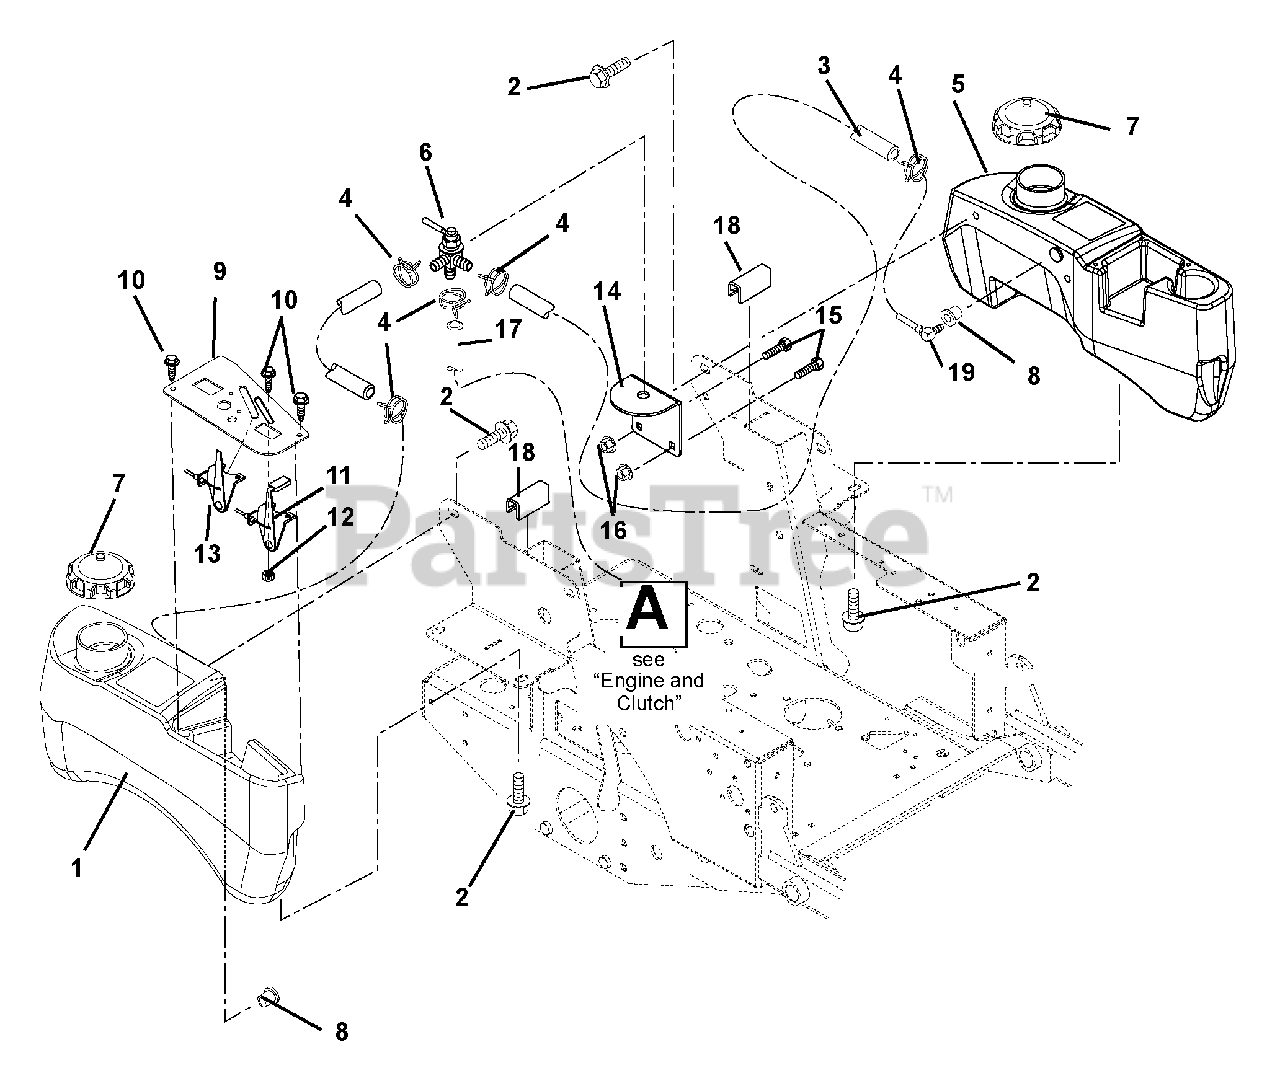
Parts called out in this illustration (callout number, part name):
1	TANK, FUEL RH W/O HOSE
2	BOLT, SEMS .31-18 X .62
3	HOSE, 5.75"-1/4" ID GAS LINE
4	CLAMP-HOSE WIRE .490/.510X.116
5	TANK, LH FUEL CZ W/O HOSE
6	VALVE, FUEL
7	CAP - FUEL
8	BSHG-FLG .375 X 1.062 X .625 R
9	PANEL, CONTROL
10	@SCR-MCH 10-24X.50 HWH YWZC
11	CABLE, THROTTLE-CHOKE
12	@NUT-LK-NYL 10-24 W/INSRT YWZC
13	CABLE, CHOKE
14	BRKT, FUEL VALVE MNTG
15	@BLT-RDHDSQNK .31-18X.75 G5YZ
16	@NUT-LK-NYL-FLG .31-18 YWZC
17	HOSE, 29"-1/4"ID GAS LINE
18	STRIP, COWL
19	ASS'Y, LARGE TANK FUEL PICK-UP
